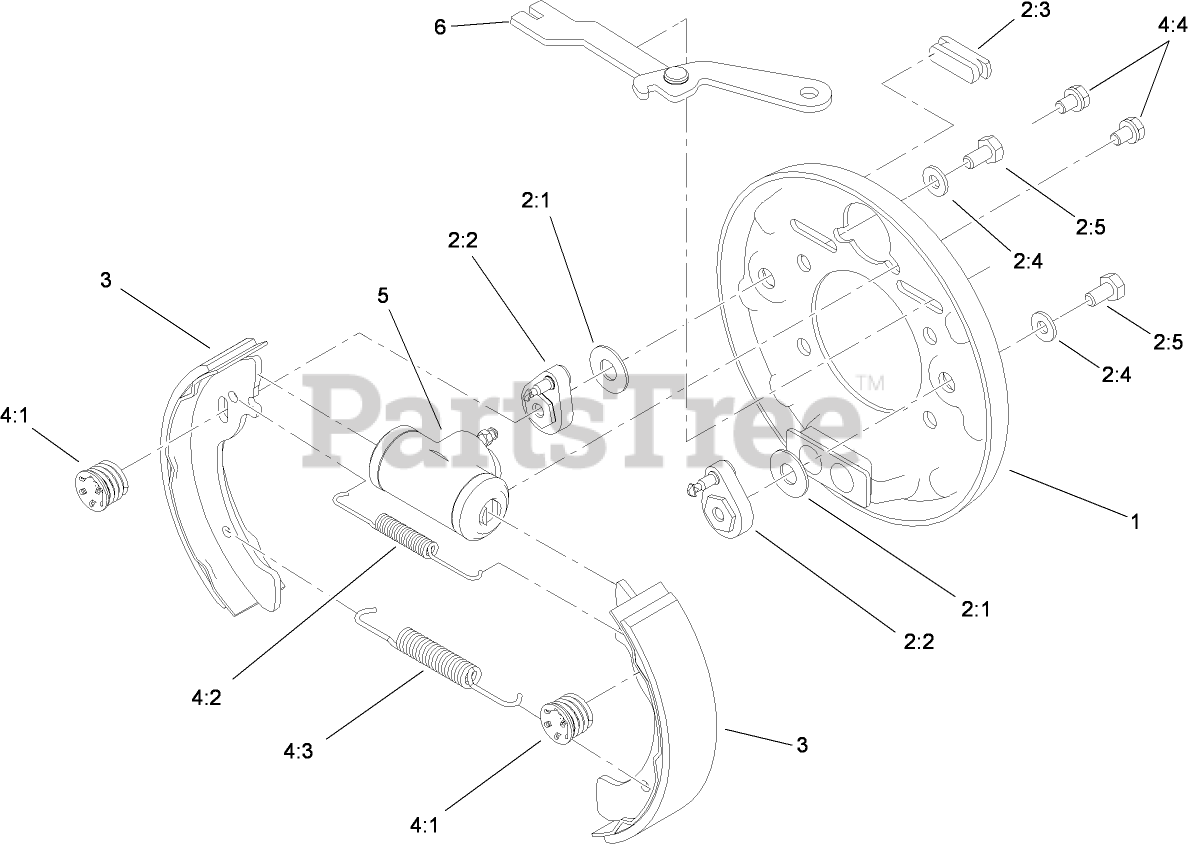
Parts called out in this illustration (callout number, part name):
1	BACKING PLATE ASM
2	ADJUSTER KIT
2:1	WASHER-BELLVILLE
2:2	ADJUSTER LEVER ASM
2:3	COVER-DUST
2:4	Washer
2:5	Bolt
3	SHOE AND LINING KIT
4	HARDWARE KIT
4:1	SHOE HOLD DOWN SPRING ASM
4:2	SPRING-UPPER
4:3	SPRING-LOWER
4:4	Loose Parts Package
5	WHEEL CYLINDER ASM
6	LH PARK BRAKE LEVER ASM
